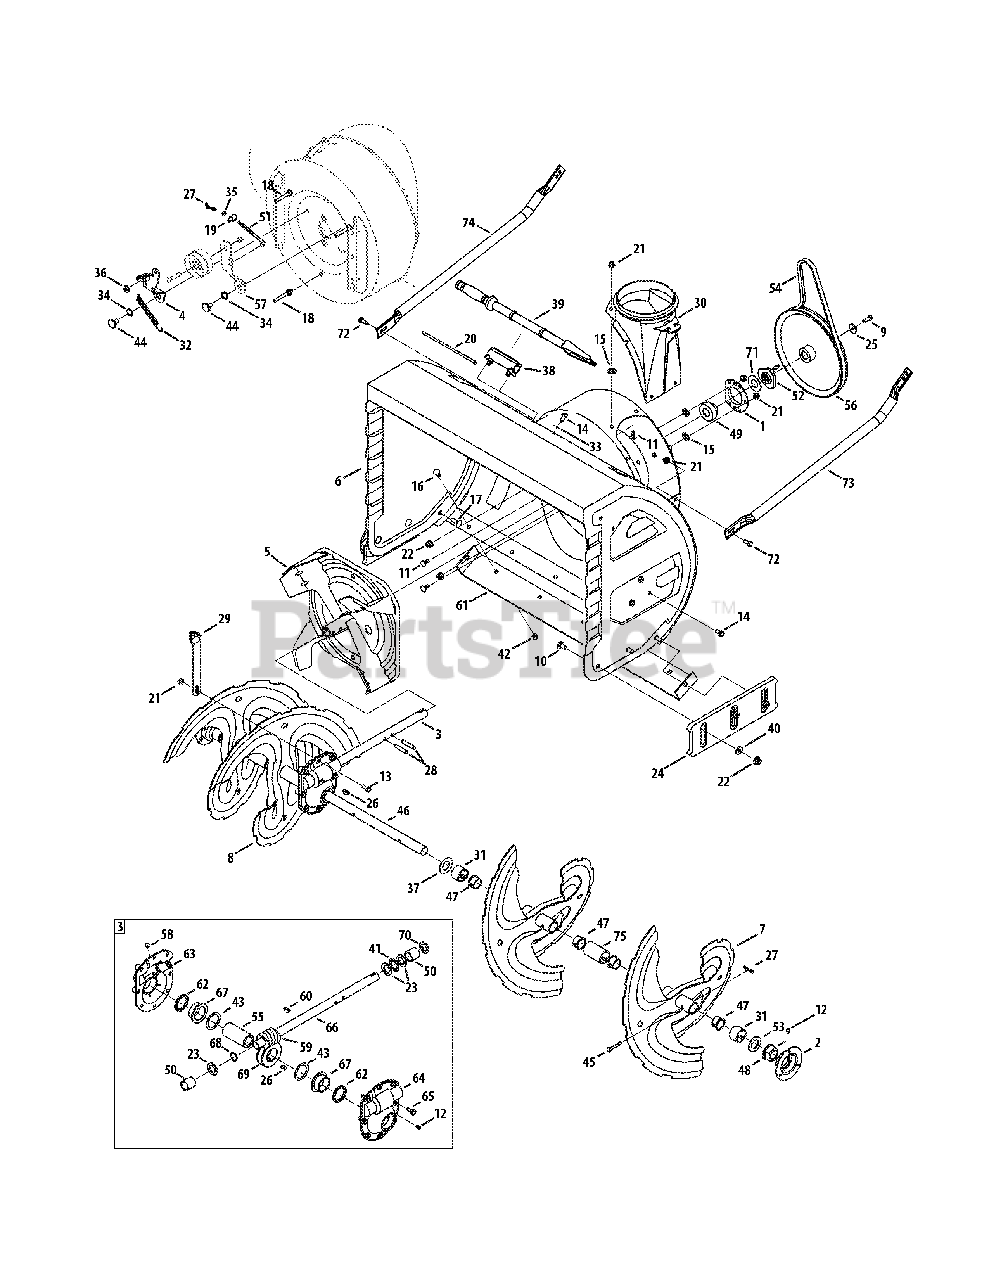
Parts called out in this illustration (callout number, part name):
1	Housing, Bearing
2	Housing, Bearing
3	Gear Box Assembly
4	Bracket Assembly, Auger Brake
5	Impeller, 16"
6	Housing, Auger - 33"
7	Spiral Assembly, LH
8	Spiral Assembly, RH
9	Screw, Hex Cap Lock, 5/16-24
10	Screw, Carriage, 3/8-16 x 1.00
11	Screw, Carriage, 5/16-18 x .75
12	Fitting, Lube
13	Screw, Hex Cap, 5/16-18 x 1.0 Gr5
14	Screw, 5/16-18 x .750
15	Nut, Push
16	Screw, Carriage, 5/16-18 x .75
17	Screw, Carriage, 3/8-16 x 1.25
18	Screw w/Stud, 5/16-18 x .4300
20	Tie Strap
21	Nut, Hex Flange Lock, 5/16-18
22	Nut, Hex Flange Lock, 3/8-16
23	Wash, Flat, .88 ID x .38 OD
24	Shoe, Skid, Deluxe
25	Washer, Flat, .34 x 1.5 x .15 Ht.
26	Key, Woodruff, 1/4 x 3/4
27	Pin, Bow-tie Cotter
28	Pin, Spiral, 5/16 x 1.75
29	Bracket, Gear Box Support
30	Adapter, Chute, 6"
31	Spacer, 1.0 x 1.5 x 1.0 Lg
32	Spring, Extension
33	Washer, Flat, .349 x .879 .063
34	Washer, Wave, .625 x .885 x .015
35	Jam Nut, 5/16-18
36	Washer, .344 x .75 x .12
37	Washer, 1.01 x 1.86 x .06
38	Clip, Mounting
39	Tool, Clean-out
40	Wash, Flat, .385 x .870 x .092
41	Bearing, Thrust
42	Nut, Hex, 5/16-18 Stainless
43	Wash, Flat, 1.52ID x 2.0 OD
44	Screw, Shoulder, .625 x .17
45	Pin, Shear, .25 x 1.75
46	Shaft, Spiral
47	Bushing, Flange,
48	Bearing, Flange w/Flats
49	Bearing, Self Aligning
51	Rod, Auger Idler
52	Adapter, Pulley w/Pins
53	Spacer, 1.004 x 1.375 x .25
54	V-Belt, 1/2 x 42
55	Shaft, Gear, Worm
56	Pulley, Auger Drive, 10.0
57	Bracket, Auger Idler
59	Gear, Worm
60	Key, Hi Pro, 3/16 x 3/4
61	Plate, Shave
63	Hsg, Ass’y, Auger RH (Incl. Ref. 62 & 67)
64	Hsg, Ass’y, Auger LH (Incl. Ref. 62 & 67)
65	Screw, LD, 5/16-18 x .750
66	Shaft, Drive, Auger
67	Flange Bearing
68	External, Retaining, Ring
69	Gear, Worm, LH
70	Seal, Oil
71	Washer, Flat, .76 x 1.49 x .06
72	Hex Cap Screw, 5/16-18 x .75
73	Support Tube, LH
74	Support Tube, RH
75	Spacer, 1.0 x 1.5 x 2.5 Lg
